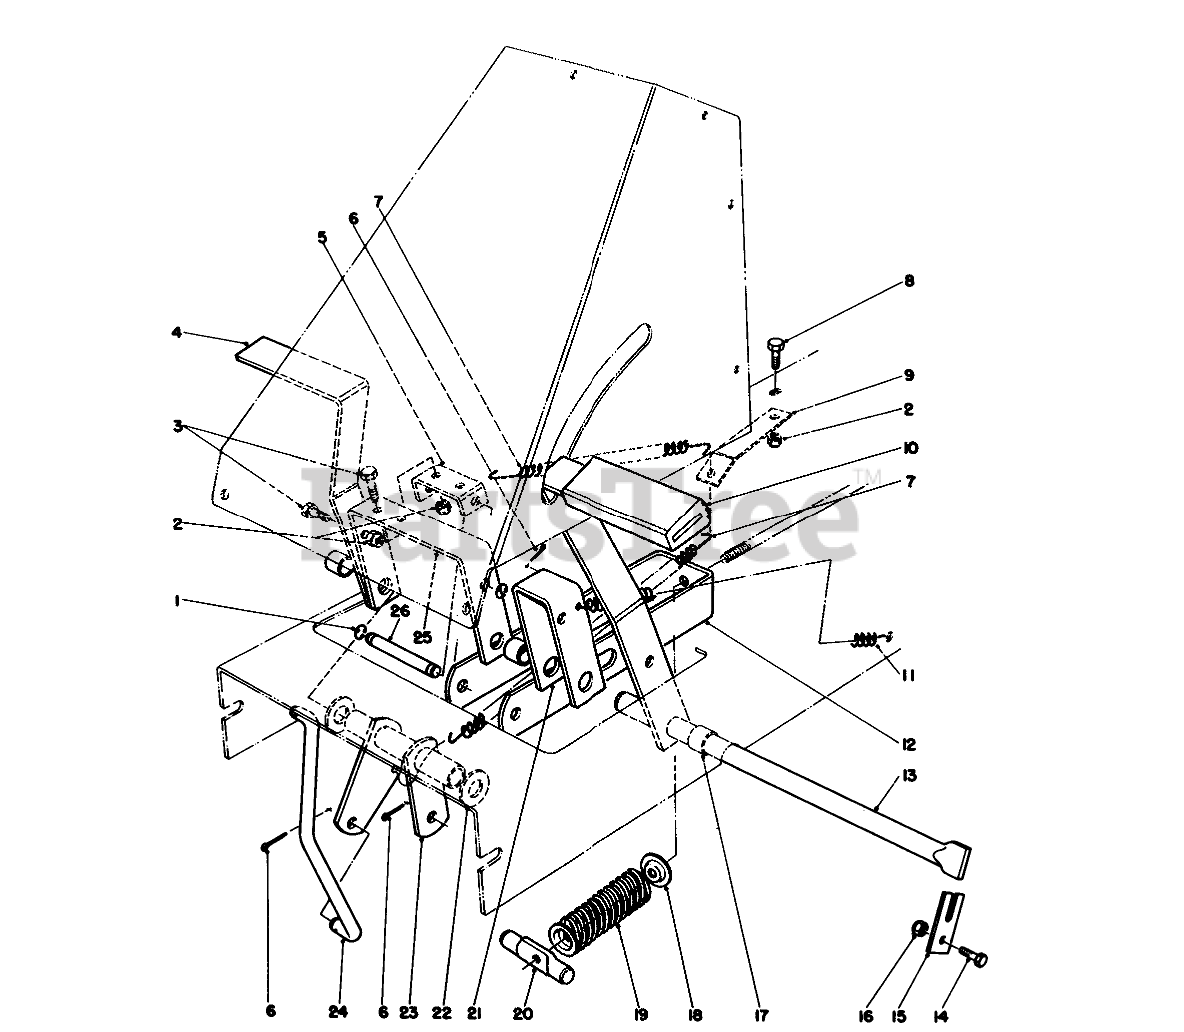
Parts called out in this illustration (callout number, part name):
1	E-RING
2	NUT-LOCK, NI
3	SCREW-HH
4	Pedal
5	Bracket-Brake
6	PIN-COTTER
7	Spring-Extension
8	SCREW-HH
9	Bracket-Spring Retaining
10	Pad-Foot Pedal
11	SPRING-EXTENSION
12	Bracket-Engagement
13	SHAFT-PEDAL PIVOT
14	SCREW-HH
15	RETAINER-SHAFT
16	NUT-LOCK, CONE
17	SPACER-PEDAL
18	RETAINER-SPR. TOP
19	SPRING-COMPRESSION
20	SHAFT-DECK ADJ.
21	Bracket-Clutch Pedal
22	WASHER-FLAT
23	Tube-Pivot
24	Arm-Engagement
25	Bracket-Brake Pedal
26	Pin-Clevis
